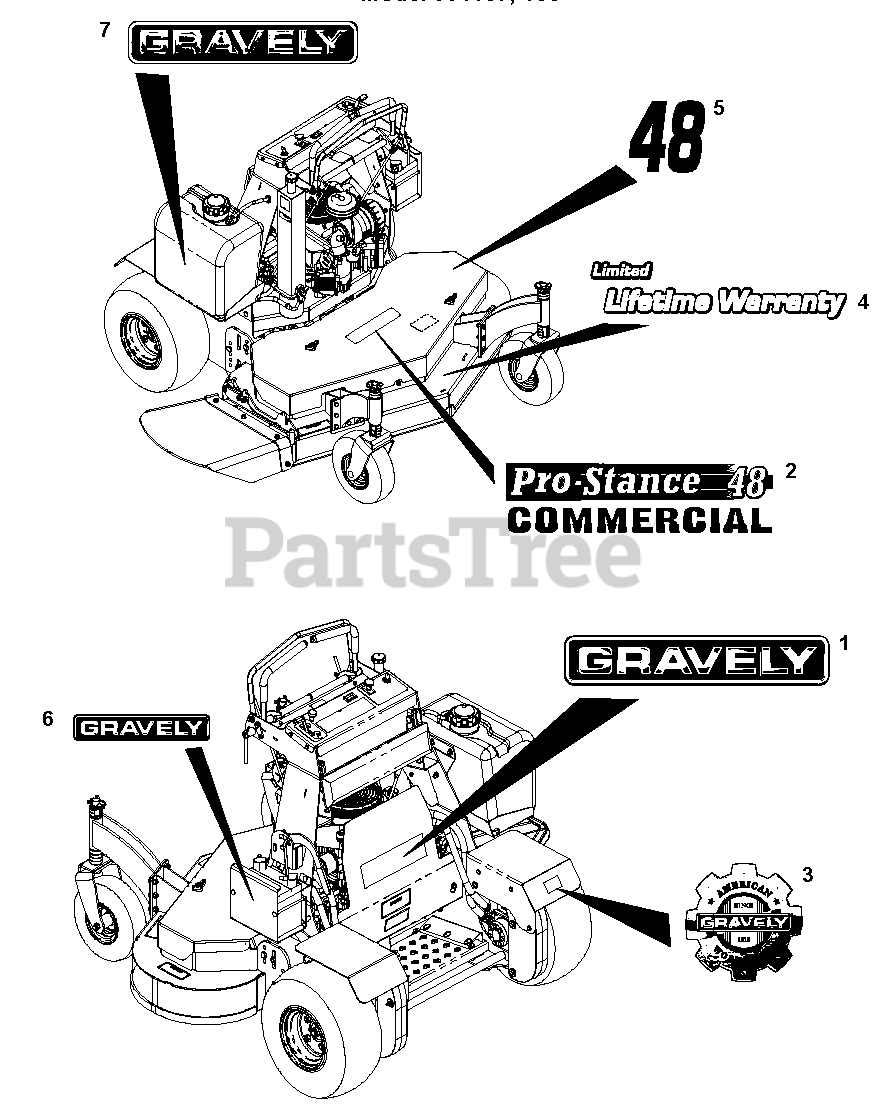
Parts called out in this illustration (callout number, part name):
1	Decal, 15" Gravely Logo
2	Decal, Pro Stance 48"
3	Decal, Gravely Heritage - Large
4	Decal, Limited Lifetime Warranty
5	Decal, 48"
6	Decal, Gravely Logo
7	Decal, Fuel Tank Gravely
